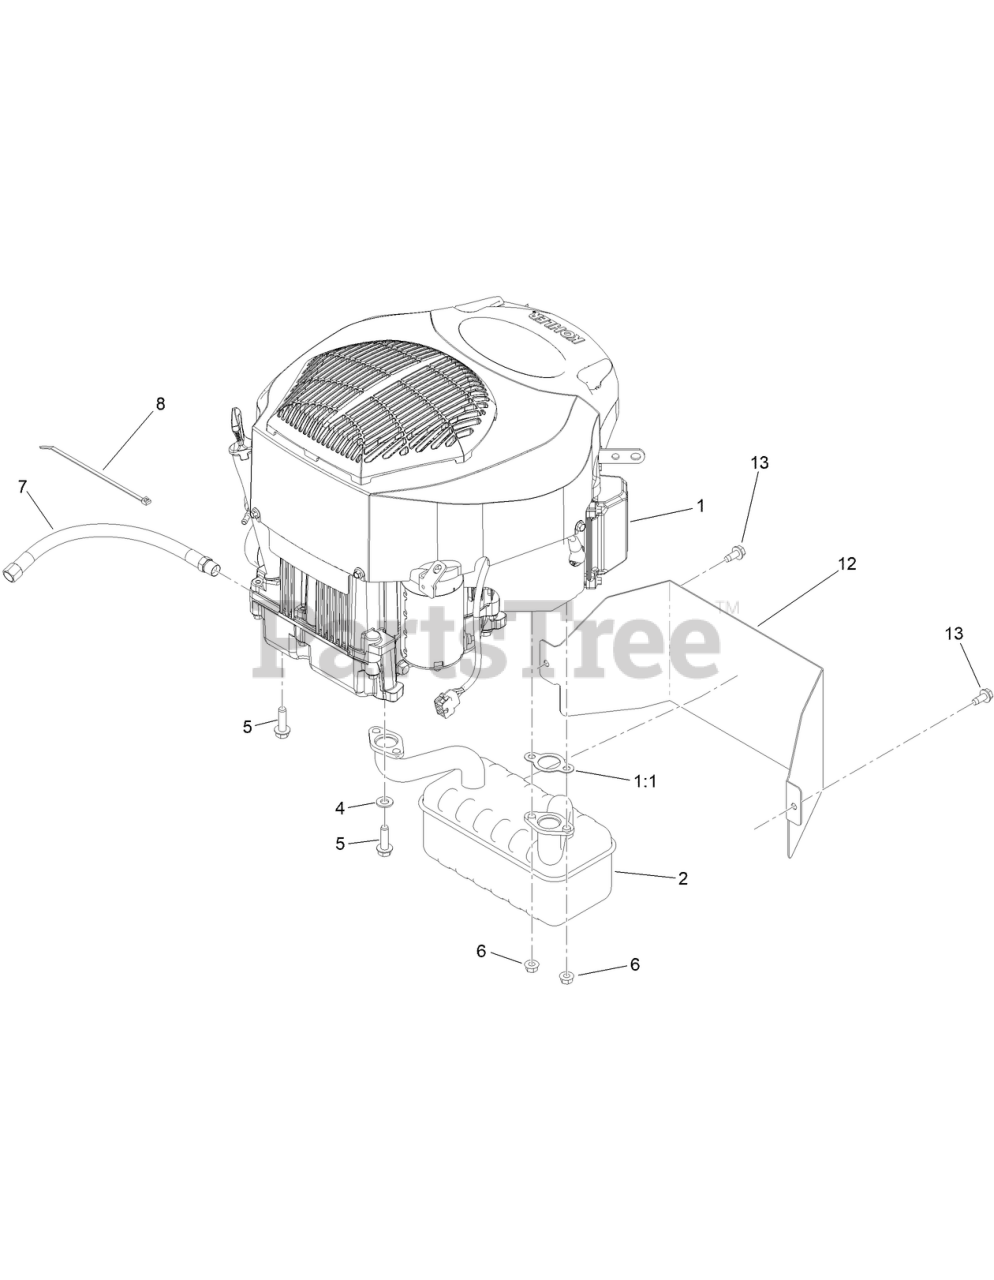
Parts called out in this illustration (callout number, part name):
1	ENGINE-KOHLER, KT735 LOW SPEED
1:1	GASKET-EXHAUST
2	MUFFLER
4	WASHER-FLAT
5	SCREW-HWH, THD ROLL
6	NUT-HF
7	HOSE-DRAIN, OIL
8	TIE-CABLE
12	HEAT SHIELD - MUFFLER
13	SCREW-HWHTF
